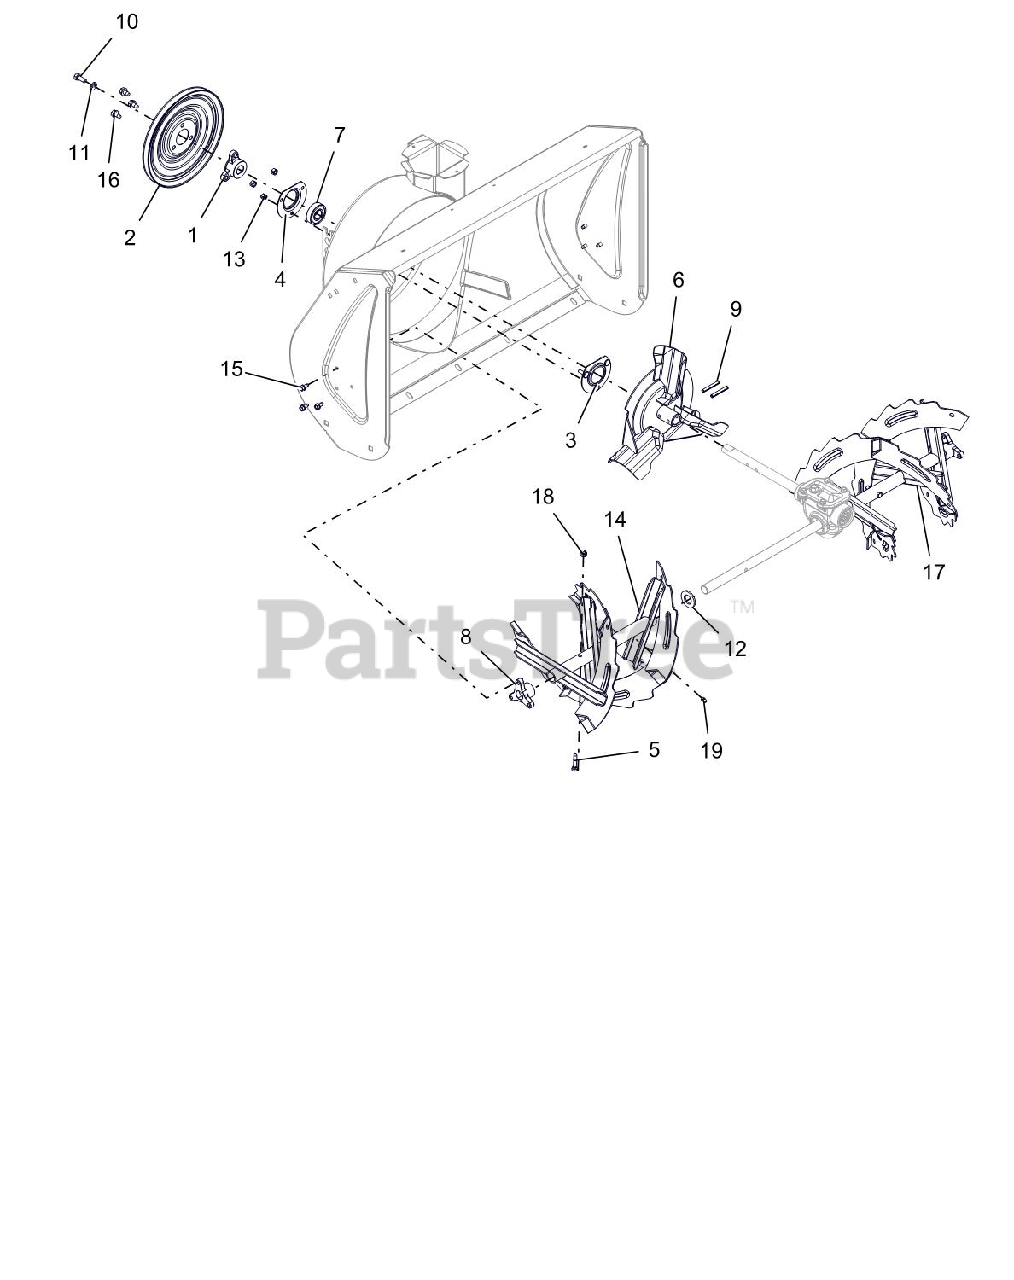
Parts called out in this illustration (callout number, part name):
1	PULLEY HUB, BOLT-ON D-BORE .75
2	PULLEY,SPIN FORM SINGLE GROOVE
3	BEARING FLANGE
4	BEARING FLANGE
5	SHEAR BOLT WITH NUT
6	IMPELLER, COMPACT 12" 3-BLADE
7	BRG-BALL .750X1.750X.50
8	BUSHING, RAKE SHAFT .75"
9	PIN-ROLL .250X1.75
10	BLT-HEX .31-24X.75 YWZC GR5
11	WSHR-LK .312X.097 HVY YWZC
12	@WSHR-FL-STL.812X1.50X.135YWZC
13	@NUT-LK-CTR .25-20 YWZC
14	RAKE, 28" RH, BLK SERR W/ZERK
15	SCR-TAP .25-20X.50 HWH TR YWZ
16	@SCR-TAP .31-18X.50 HWH TR YWZ
17	RAKE, 28" LH, BLK SERR W/ZERK
18	@NUT-LK-CTR .25-20 YWZC
19	ZERK,FITTING .25X.125 DRIVE IN
